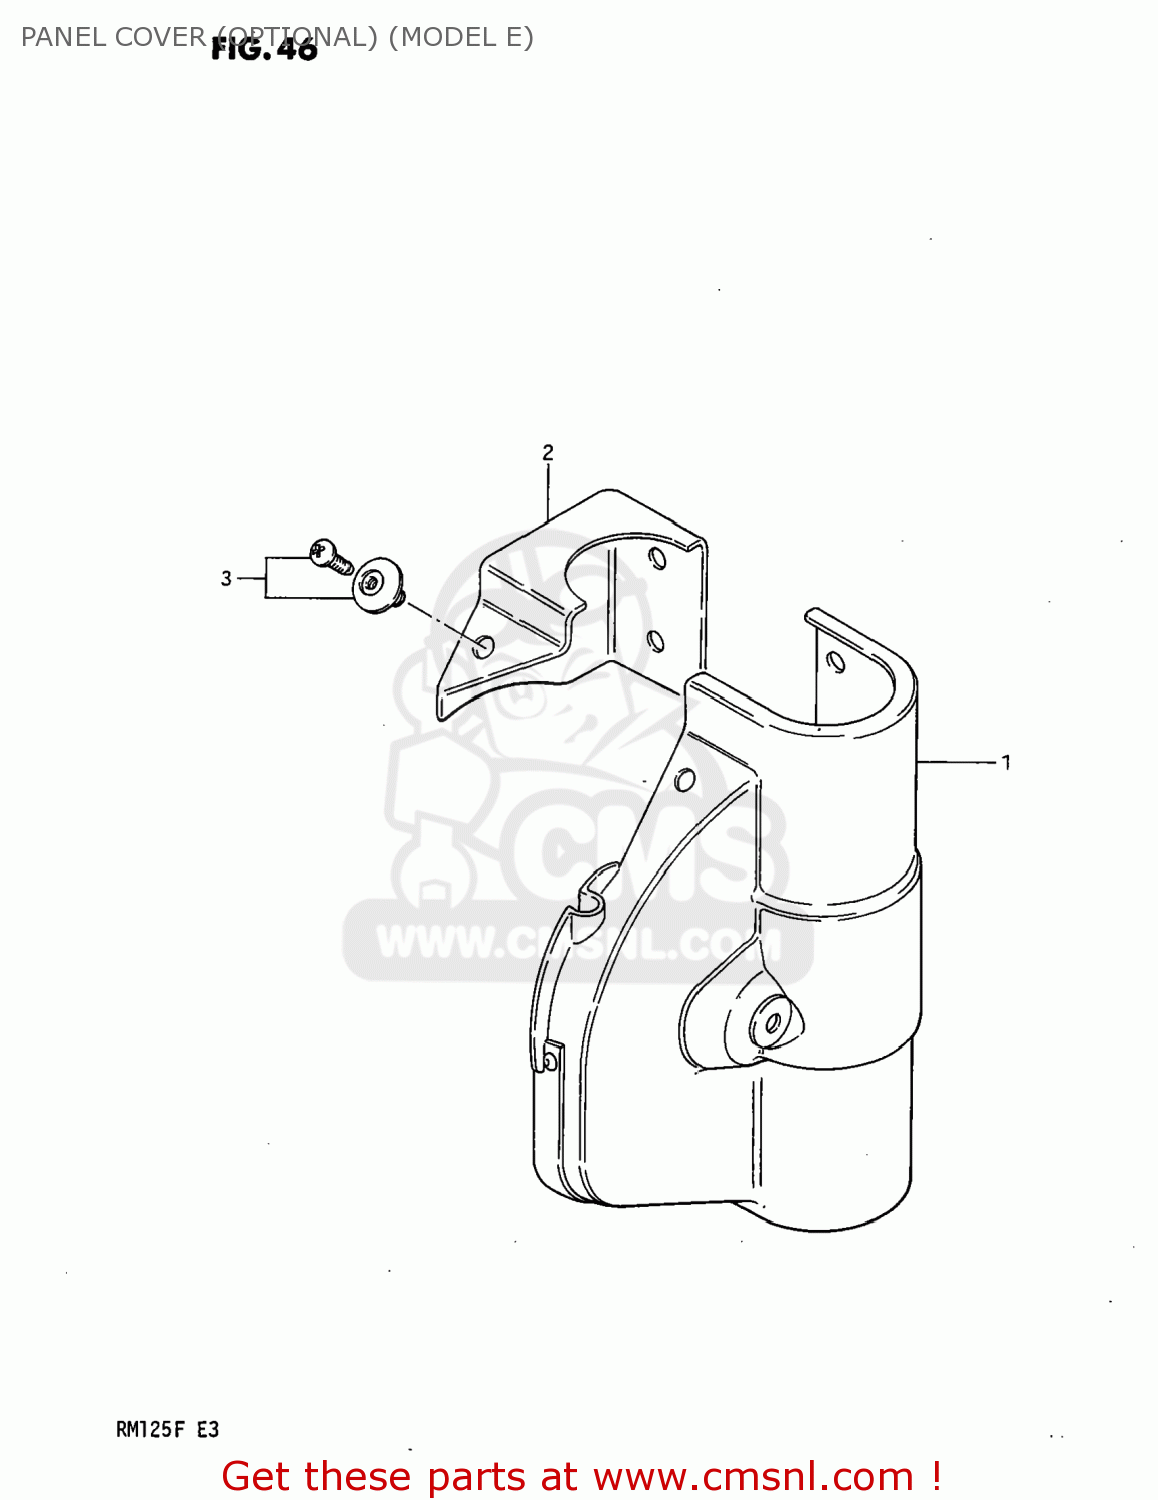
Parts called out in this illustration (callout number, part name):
1	COVER,FRONT HUB PANEL
2	CAP
3	CLIP(BLACK)
